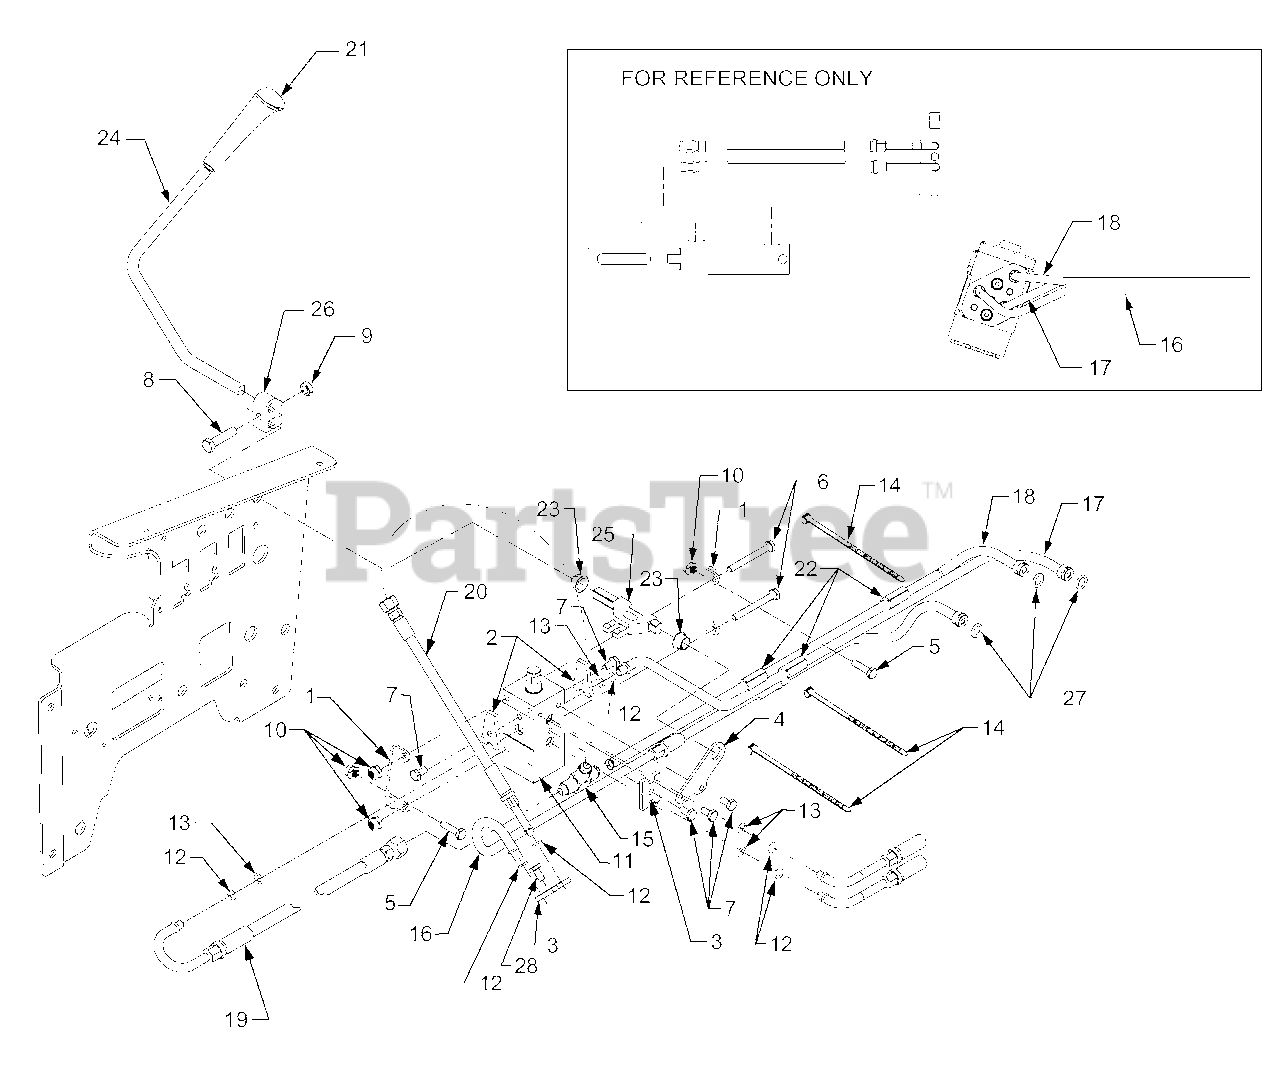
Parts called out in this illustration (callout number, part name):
1	Bracket, Valve Mounting
2	Clamp, Side Valve
3	Clamp, Double Valve
5	Screw, Hex Cap 1/4-20 x 1.0 GR5
6	Screw, Hex Cap 1/4-20 x 2.25 GR5
7	Screw, Hex Cap 1/4-20 x .50 GR5
8	Screw, Hex Cap 5/16-18 x 1.375 GR5
9	Nut, Hex Insert Lock, 5/16-18
10	Nut, Hex Flange Lock, 1/4-20
11	Valve, Hydraulic
12	O-Ring, Backup
13	O-Ring
14	Cable Tie
15	T-Fitting, 9/16-18 Thrd.
16	Tube, Hydraulic (Pump to Strng)
17	Tube, Hydraulic (Aux. from Strng)
18	Tube, Hydraulic (Strng Return)
19	Tube, Hydraulic (Aux Return)
20	Tube, Hydraulic (Return to Pump)
21	Knob, Lift
22	Rubber Spacer
23	Bearing, Nylon Flange
24	Handle, Center Lift Valve
25	Link, Lift
26	Clamp, Handle
27	O-Ring, .426 x .566 x .070
28	Screw, Hex Cap 1/4-20 x .62 GR5
